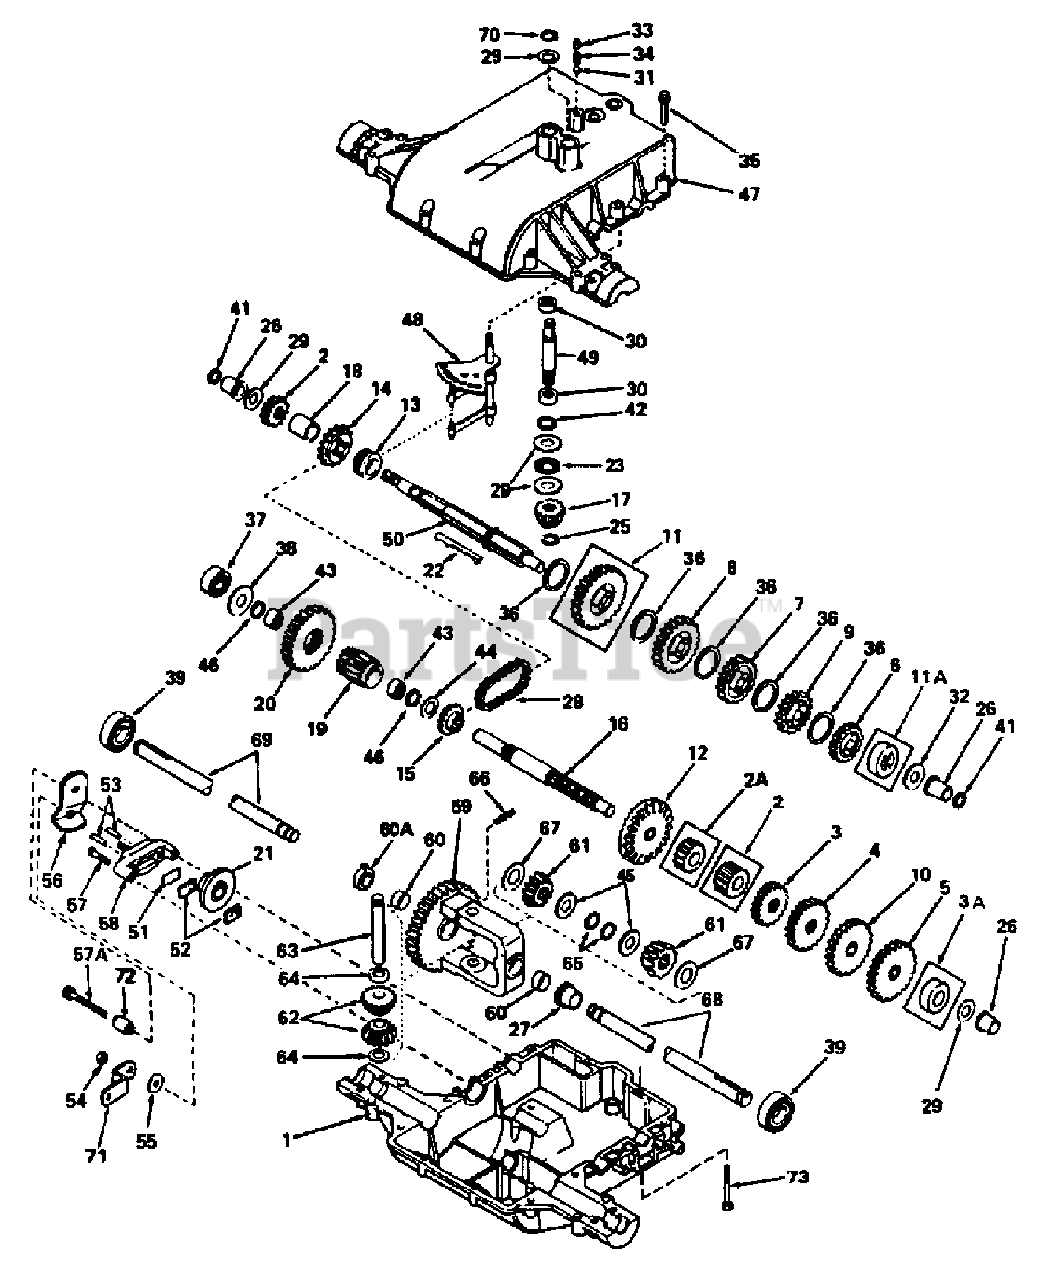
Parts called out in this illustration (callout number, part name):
1	CASE, TRANSAXLE
2	GEAR, SPUR(15 TEETH)
3A	SPACER
4	GEAR, SPUR(20 TEETH)
5	GEAR, SPUR(28 TEETH)
6	GEAR, SPUR(22 TEETH)
7	GEAR, SPUR(30 TEETH)
8	GEAR, SPUR(35 TEETH)
9	GEAR, SPUR(25 TEETH)
11	GEAR, SPUR(37 TEETH)
11A	SPACER
12	GEAR, BEVEL(42 TEETH)
13	COLLAR, SHIFT
14	SPROCKET(18 TEETH)
15	SPROCKET(9 TEETH)
16	SHAFT, COUNTER
17	BEVEL PINION, INPUT
18	SPACER
19	PINION, OUTPUT
20	GEAR, OUTPUT
21	DISK, BRAKE
23	BEARING, THRUST
25	RING, RETAINING
26	BUSHING, FLANGED
27	BUSHING, FLANGED
28	CHAIN, ROLLER(NO. 41 CHAIN, 24 LINKS)
29	WASHER, THRUST
30	BEARING, NEEDLE
31	BALL, STEEL
32	WASHER, THRUST
33	SCREW, SET, 3/8-16 X 3/8
34	SPRING
35	SCREW, HEX HD. THREAD FORMING,
36	WASHER, THRUST
37	BEARING, BALL
38	WASHER, FLAT
39	BEARING, BALL
41	RING, SQUARE CUT
42	RING, SQUARE CUT
43	BEARING, NEEDLE
44	WASHER, FLAT
45	WASHER
46	RING, SQUARE CUT
47	COVER, TRANSAXLE
48	ROD & FORK ASSEMBLY, SHIFT
49	SHAFT, INPUT
50	SHAFT BRAKE
51	PLATE, BRAKE PAD
52	PAD, BRAKE
53	PIN, DOWEL
54	LOCKNUT, 5/16-24
55	WASHER, FLAT
56	LEVER, BRAKE
57	SCREW, HEX HD. THREAD FORMING,
57A	SCREW, HEX HD. THREAD FORMING
58	HOLDER, BRAKE PAD
59	GEAR ASSEMBLY, DIFFERENTIAL
60	BUSHING
60A	BUSHING
61	GEAR, BEVEL
62	PINION, BEVEL
63	PIN, DRIVE
64	WASHER, THRUST
65	RING, RETAINING
66	PIN, ROLL
67	WASHER, THRUST
68	AXLE(22-5/8" LONG)
69	AXLE(12-7/8" LONG)
70	RING, RETAINING
71	BRACKET, BRAKE LEVER
72	SPACER
73	SPECIAL BOLT
